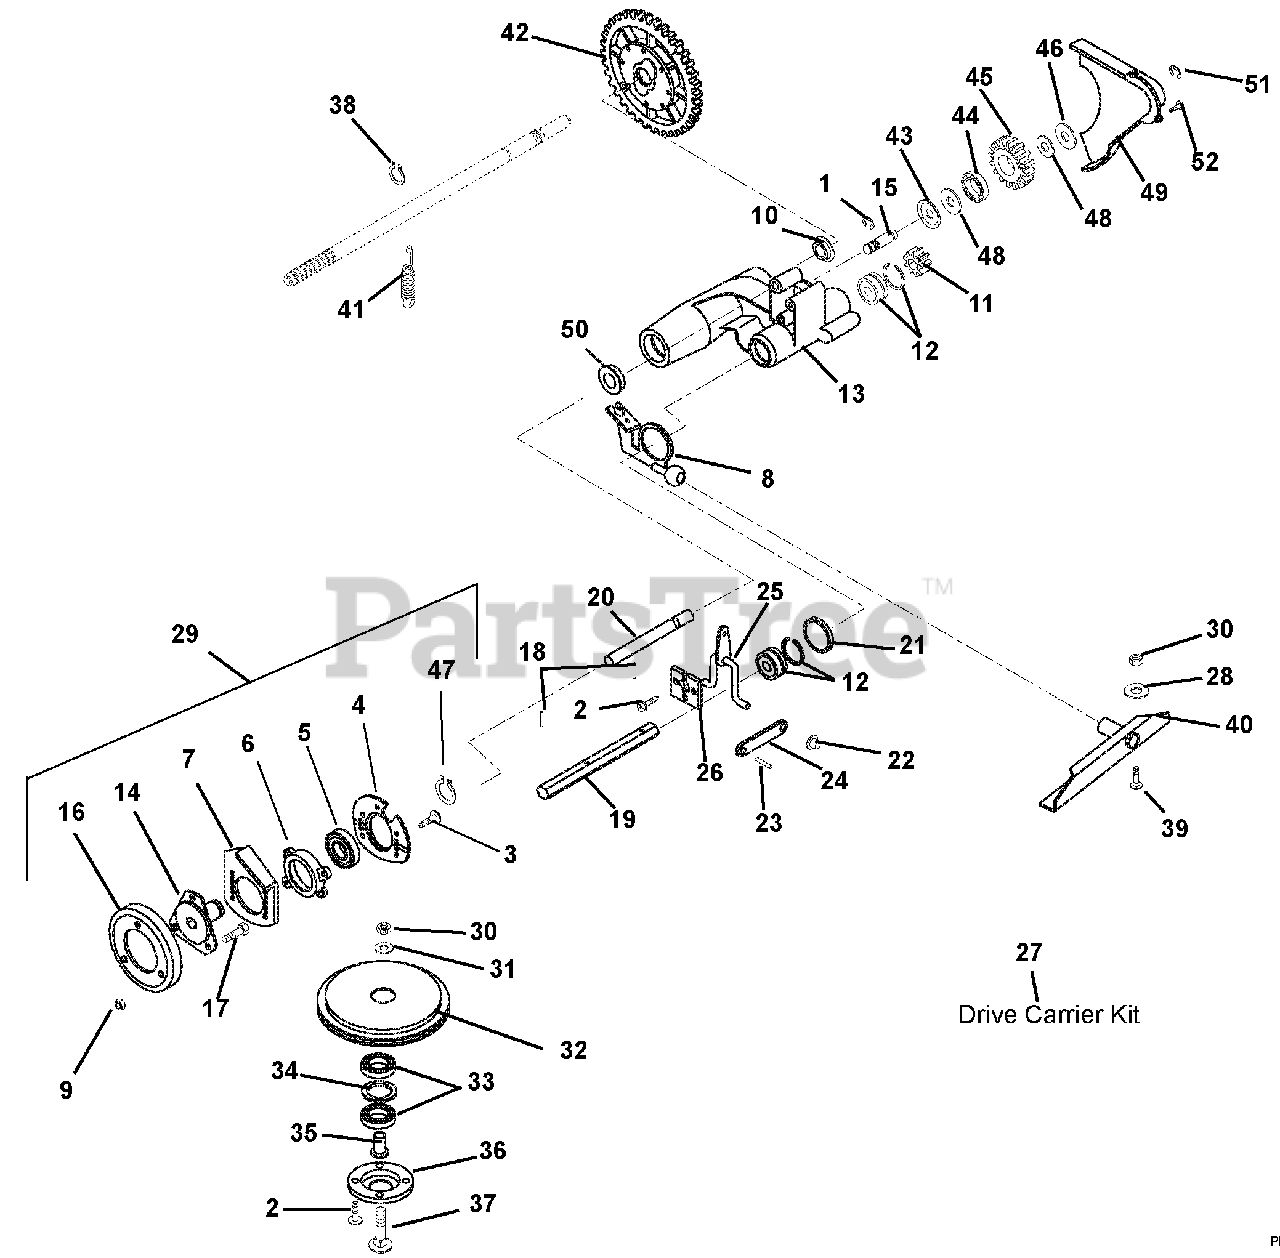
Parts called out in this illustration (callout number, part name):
1	RG-RTNG-EXT .438X.035
2	@SCR-TAP 12-24X.50 HWH TR YWZC
3	SCR-TAP 5HX-0.8X16MM H-FL-YWZC
4	BEARING RETAINER
5	BRG-BALL 1.0X2.0X.56 (1641)
6	BEARING RETAINER
7	PLATE, BEARING
8	DRIVE ACTUATOR WELDMENT
9	@NUT-LK-CTR .25-20 YWZC
10	BRG-BALL .625X1.378X.44
12	BRG-BALL .562X1.375X.437
13	DRIVE CARRIER
14	FRICTION WHEEL HUB
15	IDLER SHAFT
16	DISC, FRICTION - 730 MAT'L
17	@BLT-HEX .25-20X.50 GR5 YWZC
18	PIN-ROLL .188X.88
19	SHAFT, HEX
20	ROD - GUIDE
21	WSHR-FL-STL 1.390X2.00X.020 PL
22	PUSH NUT, .25
23	PIN-ROLL .125X.50
24	SHIFT LINK
25	SHIFT ARM WELDMENT
26	RETAINER PLATE
27	KIT, LM DRIVE CARRIER
28	@WSHR-FL-STL.344X.688X.065YWZC
29	FRICTION WHEEL ASSEMBLY
30	@NUT-LK-CTR .31-18 YWZC
31	WSHR-FL-STL .328X.87X.179 YWZC
32	FRICTION SHEAVE
33	BRG-BALL .625X1.375X.43
34	WSHR-FL-STL 1.062X1.344X.032PL
35	SPINDLE - BEARING
36	RETAINER - BEARING
37	@BLT-RDHDSQNK .31-18X1.75 G5YZ
38	RG-RTNG-EXT .579X.035
39	@BLT-RHDSSQNK .31-18X.62 G5YZ
40	PIVOT, CHANNEL WELDMENT
41	SG-TENS .051X.60X2.25 WLD 7.0
42	DIFFERENTIAL ASSEMBLY
43	RETAINER
44	BRG-BALL .500X1.38X.437
45	IDLER GEAR
46	WSHR-FL-STL.531X1.00X.063 YWZC
47	RG-RTNG-EXT 1.00X.042
48	WSHR-FL-STL .52X.827X.062 YWZC
49	COVER, GEAR
50	BRG-BALL .625X1.383X.50
51	RG-RTNG-EXT .438X.035
52	@SCR-TAP 12-24X.50 HWH TR YWZC
